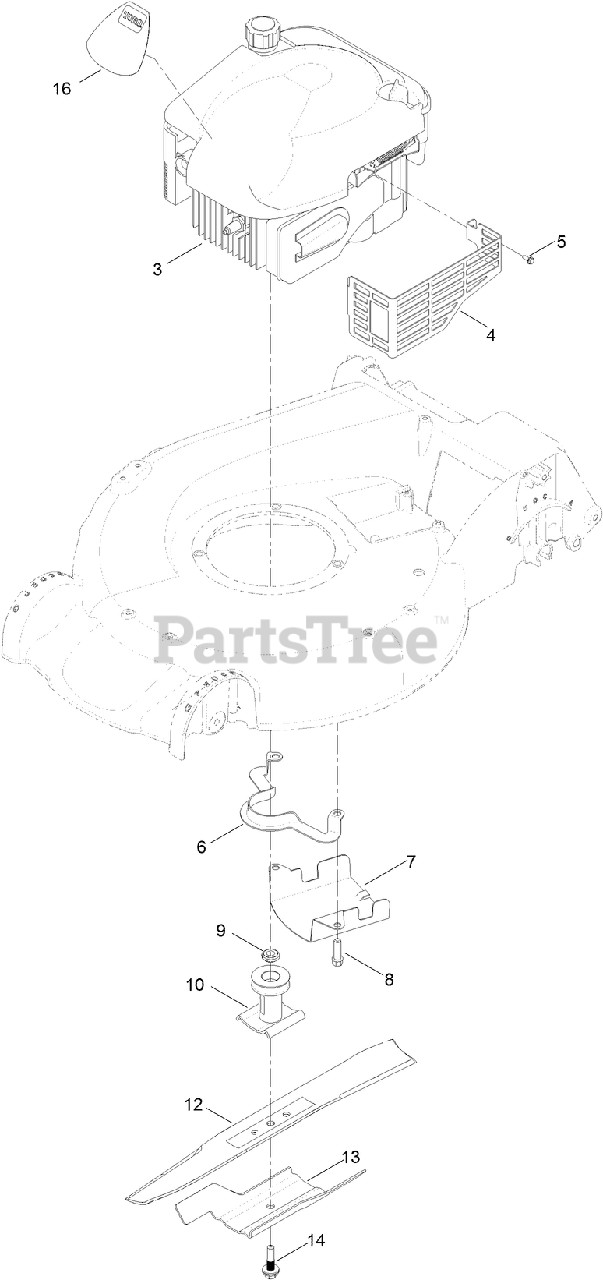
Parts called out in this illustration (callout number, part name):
4	SHIELD-MUFFLER
5	SCREW-TAPTITE
6	GUIDE-BELT
7	SHIELD-GRASS
8	SCREW-TAPTITE
9	Spacer-Driver
10	DRIVER-BLADE
12	BLADE-RECYCLING
13	Accelerator-Blade
14	BOLT-BLADE
16	DECAL-SHROUD
